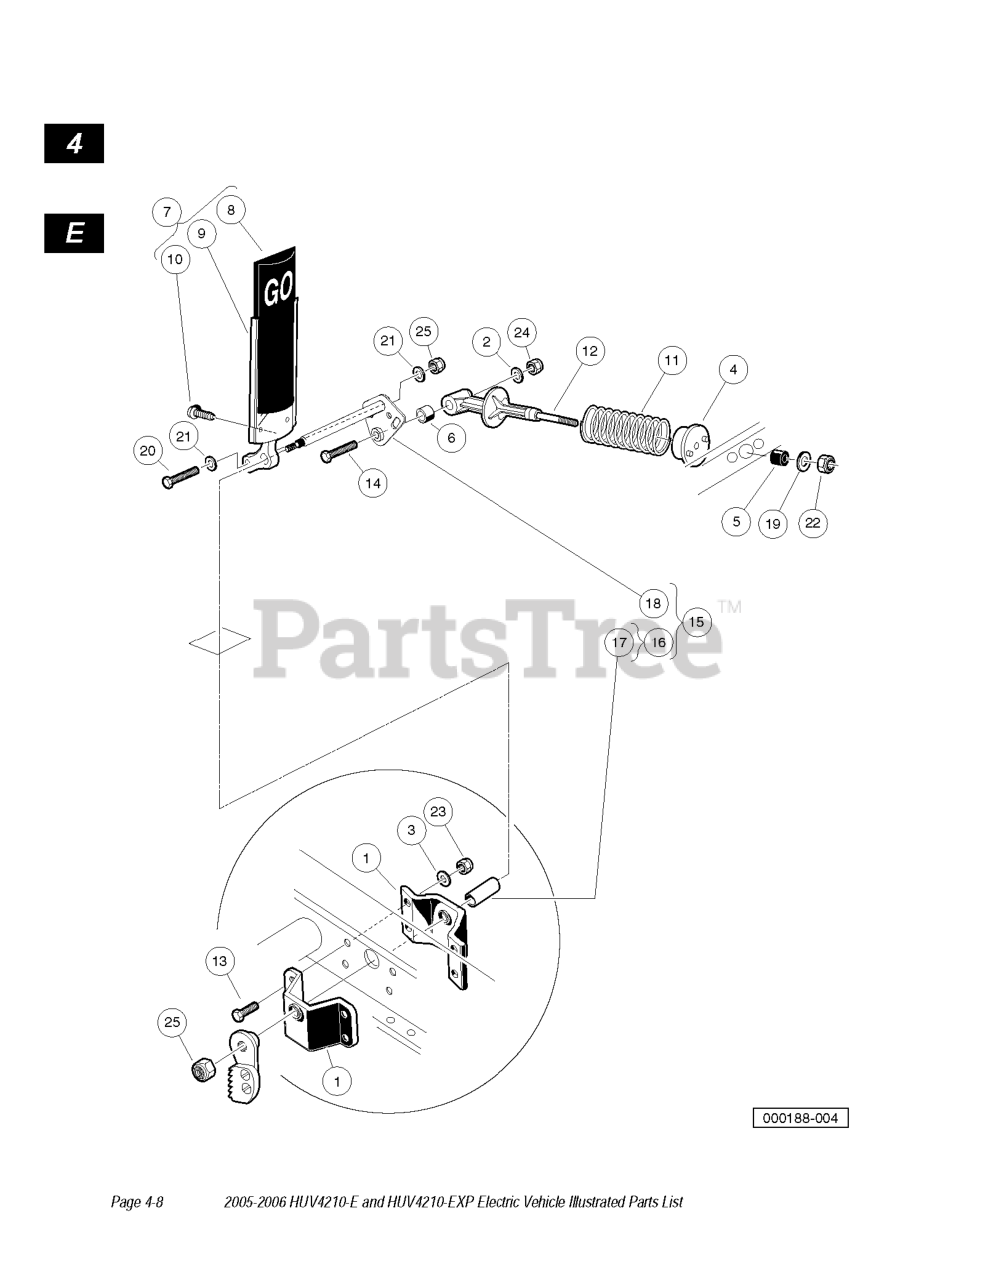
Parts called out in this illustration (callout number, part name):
1	ACCEL BRKT & BEARING ASSY
2	WASHER, 1/4 FLAT
4	CUP, SPRING
5	BUMPER, SPRING RETURN
6	BEARING, PIVOT SUPPORT
7	SUB ASM, ACCELERATOR PEDAL
8	PAD , ACCL PEDAL
10	SCREW TYPE AB SHT MTL
11	SPRING, ACCELERATOR RETURN
12	RETAINER, SPRING
13	SCREW, 1/4-20 X 1.125 HEX CAP
14	SCREW, 1/4-20 X 1.500 FLANGE
15	ACCEL. PIVOT ROD ASM. KIT
16	SPACER ASSEMBLY
19	WASHER, 5/16 TYPE A FLAT
20	SCREW, 3/8-16 X 1.5 HX HD CAP
21	WASHER, 3/8 FLAT
22	LOCKNUT, 5/16-18 NYLON INSERT
23	LOCKNUT, 1/4-20 NYLON INSERT
24	LOCKNUT, 1/4-28 NYLON INSERT
25	LOCKNUT, 3/8-16 HEX
